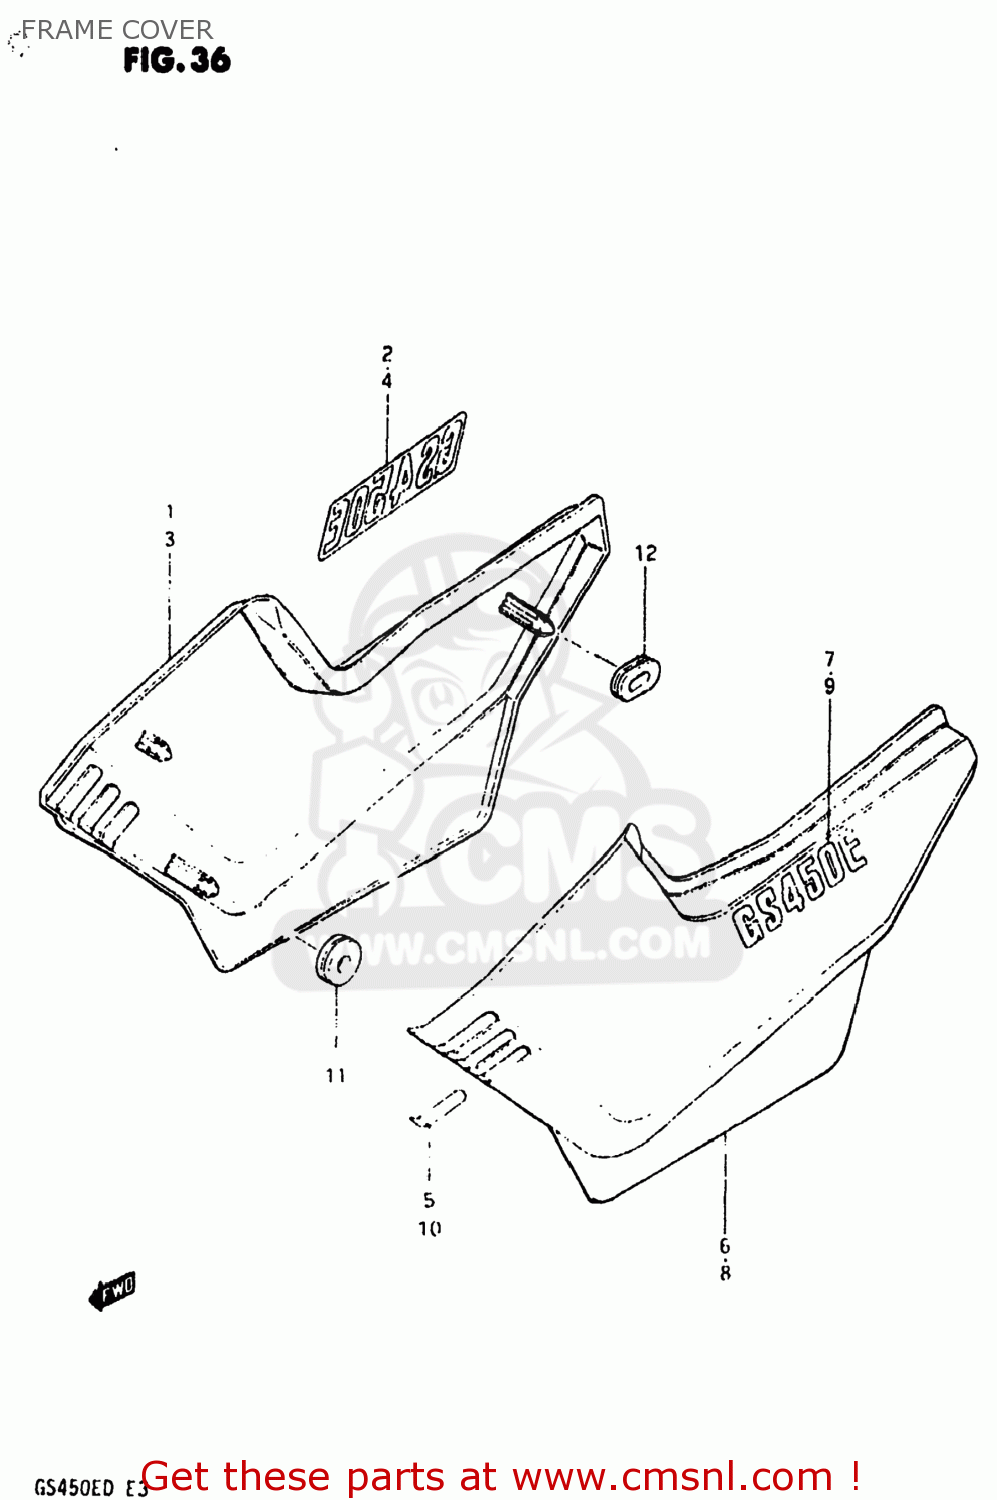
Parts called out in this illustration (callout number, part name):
1	COVER,FRAME,RIGHT
2	EMBLEM,FRAME COVER
3	COVER,FRAME,RIGHT
4	EMBLEM,FRAME COVER
5	LABEL,FRAME COVER DENT
6	COVER,FRAME,LEFT
7	EMBLEM,FRAME COVER
8	COVER,FRAME,LEFT
9	EMBLEM,FRAME COVER
10	LABEL,FRAME COVER
11	CUSHION
12	CUSHION
